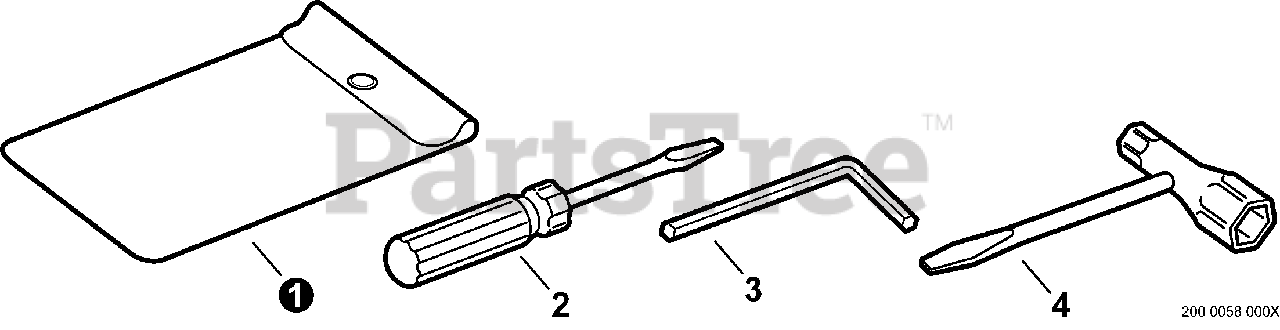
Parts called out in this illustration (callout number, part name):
1	BAG, TOOL
2	SCREWDRIVER, PHILLIPS
3	WRENCH, ALLEN 4 MM
4	T-WRENCH 13×19 L= 180
